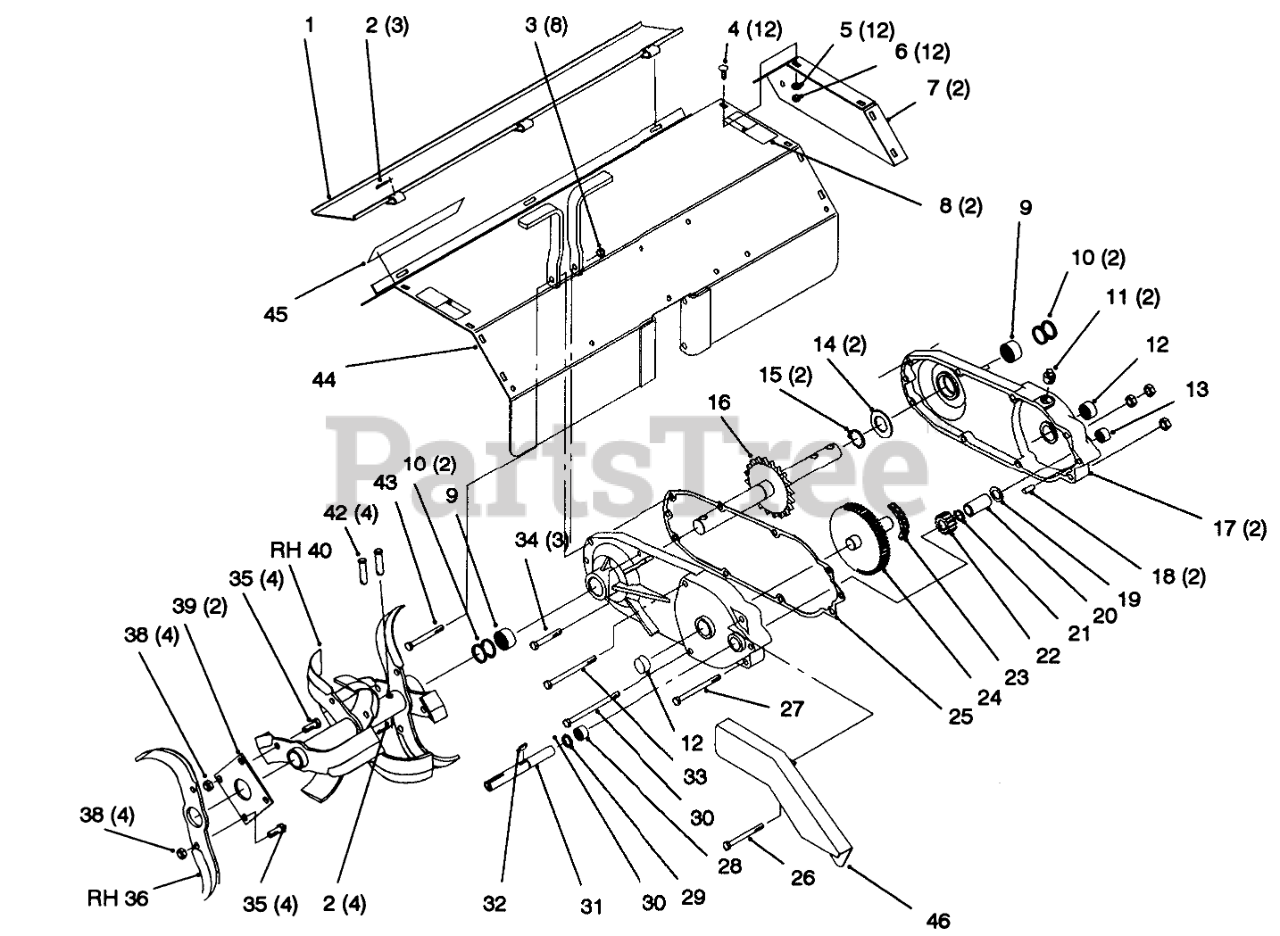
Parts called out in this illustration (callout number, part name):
1	GUARD ASM
2	PIN-COTTER
3	NUT-LOCK, NI
4	BOLT-CARR
5	WASHER-PLAIN
6	NUT-LOCK, NI
7	COVER-TINE END
8	DECAL-DANGER
9	BEARING-NEEDLE
11	PLUG-PIPE, SQH
12	BEARING-NEEDLE
13	BEARING-NEEDLE
14	WASHER
15	RING-RETAINING
16	TINE SHAFT ASM
17	GEAR CASE TILLER RED
18	PIN-ROLL
19	WASHER-THRUST
20	TUBE-SPACER
21	Ring-Snap
22	GEAR-PINION
23	CHAIN
24	GEAR AND SHAFT ASM
25	GASKET-TRANSMISSION
26	SCREW-HH
27	SCREW-HH
28	BEARING-NEEDLE
29	SEAL-OIL
30	SCREW-HH
31	SHAFT-INPUT
32	KEY-WOODRUFF
33	SCREW-HH
34	SCREW-HH
35	SCREW-HH
36	TINE-RH
37	TINE-LH
38	NUT-LOCK, NI
39	PLATE-TINE MOUNTING
40	RH TINE ASM
41	LH TINE ASM
42	PIN-CLEVIS
43	SCREW-HH
44	Shield W/Safety Decal
45	DECAL-ATTACHMENT
46	Guard-Tiller
